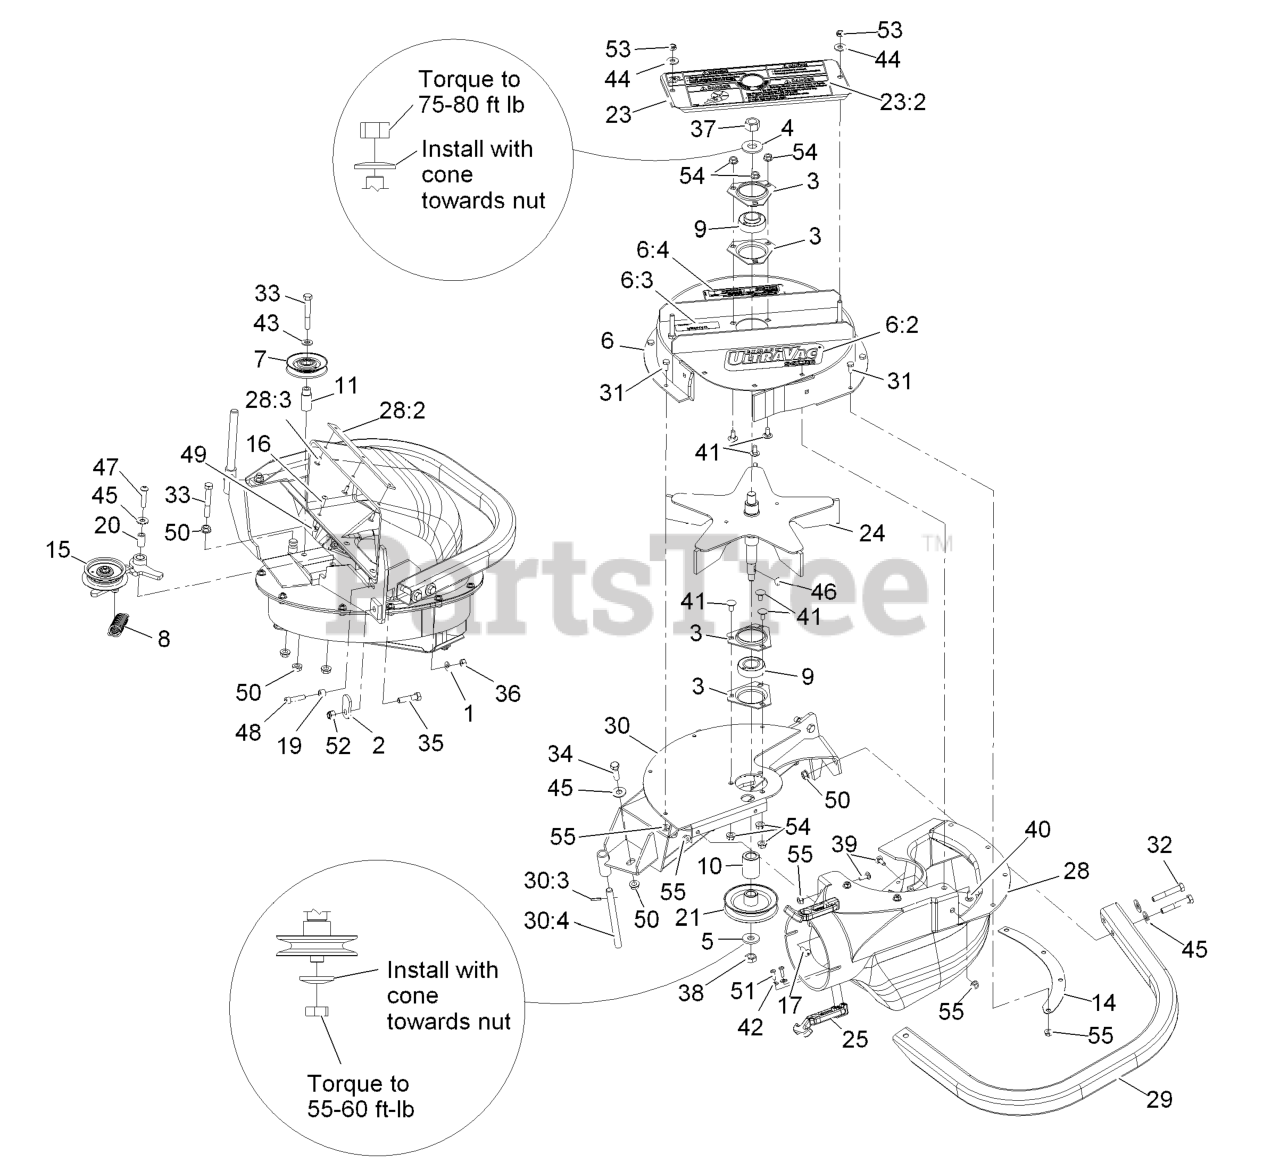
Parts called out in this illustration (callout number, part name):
1	WASHER-SPRING
2	LATCH-CATCHER, GRASS
3	HOUSING-FLANGE
4	WASHER-SPRING
5	WASHER-SPRING
6	ASM-UPPER HOUSING SMALL
6:2	DECAL-ULTRA VAC S-SERIES
6:3	DECAL-COVER, MISSING
6:4	DECAL,WEIGHT
7	IDLER-INSIDE
8	SPRING-IDLER
9	BEARING
14	PLATE-BACKING, BLOWER
15	Asm, Idler
16	SCREW-HEAD, TRUSS
19	BUSHING, LOCATOR
20	BUSHING-PIVOT, IDLER
21	SHEAVE-BLOWER
23	ASM, BEARING COVER
23:2	DECAL-WARNING
24	IMPELLER
25	LATCH-RUBBER
28	ASM,BLOWER CHUTE LHP
28:2	PLATE-REINFORCEMENT
28:3	RIVET-BLIND
30	WELD, FRAME SM BLOWER
30:3	PIN-ROLL
30:4	SHAFT-CATCHER, GRASS
31	SCREW-HH
32	SCREW-HH
33	BOLT-CARR
34	SCREW-HH
35	SCREW-HH
36	NUT-HEX
37	NUT-HEX
38	NUT-JAM
39	BOLT-CARR
40	SCREW-CARR
41	SCREW-CARR
42	WASHER-FLAT
43	WASHER-FLAT
44	WASHER-FLAT
45	WASHER-FLAT
46	KEY-WOODRUFF
47	SCREW-HSBH
48	SCREW-HSH
50	NUT-HHF, WHIZ
51	SCREW-PPH
52	NUT-LOCK, NI
53	NUT-LOCK, NI
